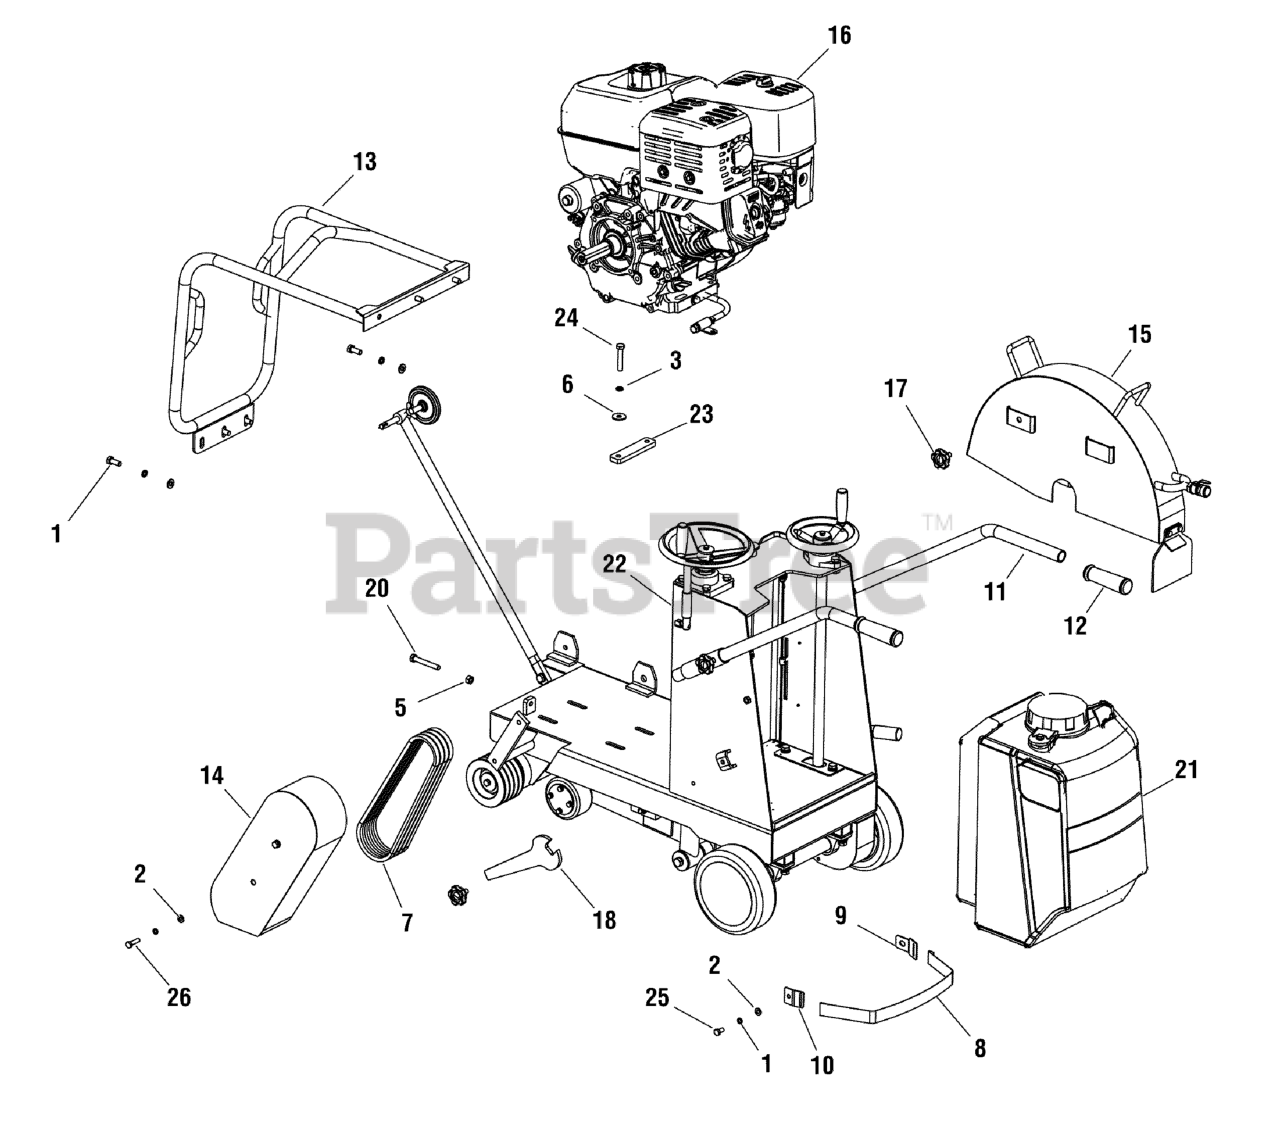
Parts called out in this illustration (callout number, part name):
1	WASHER, Spring, 8
2	WASHER, Flat, 8
3	WASHER, Spring, 10
4	WASHER, Flat, 10
5	NUT, Hex, M10
6	WASHER, Flat, Large
7	V-BELT
8	ELASTIC BANDAGE
9	BANDAGE HOOK
10	BANDAGE FIXED PLATE
11	SHEATH, Handle
12	HANDLE
13	FRAME, Lifting
14	COVER, Belt
15	BLADE COVER ASSEMBLY
16	ENGINE ASSEMBLY
17	KNOB, Bolt, M10
18	SPANNER
19	BOLT, Hex, M10 x 25
20	BOLT, Hex, M10 x 70
21	WATER TANK ASSEMBLY
22	FRAME ASSEMBLY, Water Tank
23	ENGINE RETAINER PLATE
24	BOLT, Hex, M10 x 55
25	BOLT, Hex, M8 x 16
26	BOLT, Hex, M8 x 30
